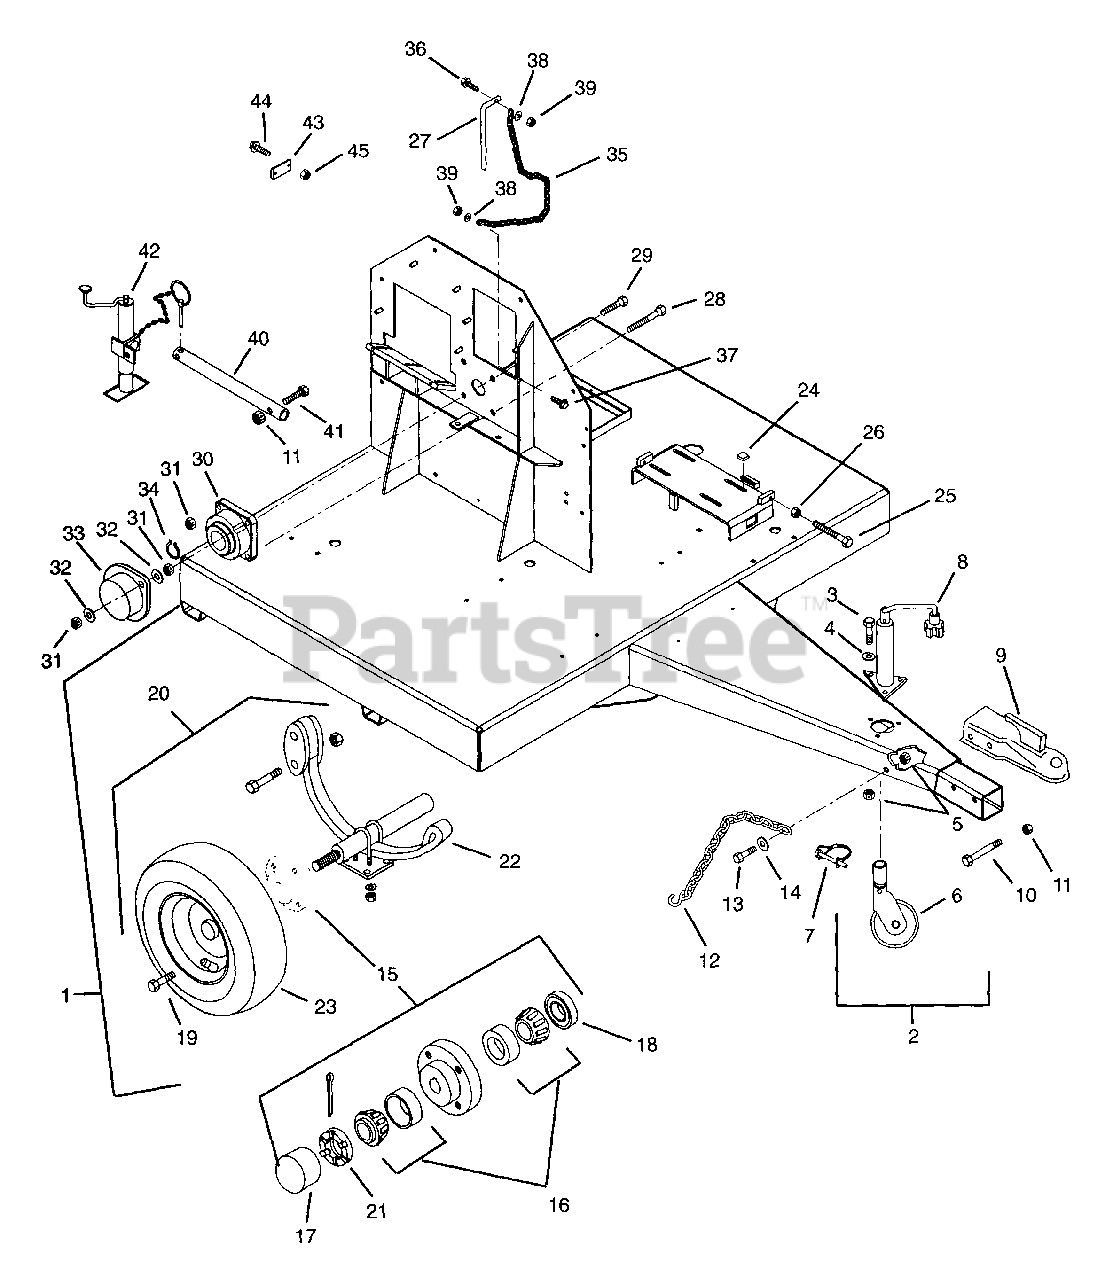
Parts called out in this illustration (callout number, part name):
1	Trailer Bed, Complete
2	Jack Assembly
3	Bolt-Hex .44-14 x 1.25 Grade 5
4	Washer-Flat-Steel .50 x 1.25 x .083
5	Nut-Locking-Center .44-14
6	Swivel Wheel
7	Quick Latch Pin, Jack Wheel
8	Pillow Jack Assembly - Less Wheel
9	2" Coupler Ball Type
10	Bolt-Hex .50-13 x 3.75 Grade 5
11	Nut-Locking-Center .50-13
12	Safety Chain,
13	Bolt-Hex .44-14 x 1.00 Grade 5
14	Washer-Flat-Steel .50 x 1.25 x .083
15	Axle Hub, Complete
16	Bearing Replacement Assembly
19	Bolt-Hex .50-20 x .75 x 1.62
20	Trailer Axle, Complete - Less Tire and Wheels
21	Nut-Slotted 1.0-14
22	Axle Spring
23	Tire and Wheel Assembly
24	Key-Straight .38 x 2.75 x .38
25	Bolt-Hex .38-16 x 3.5
26	Nut-Hex .38-16
27	Pin-Arbor Shaft Lock
28	Bolt-Lug .50-20 x 2.50
29	Bolt-Lug .50-20 x 1.50
30	Bearing-Flange 1.500 x 4 Bolt x 2.047
31	Nut-Locking-Center .50-20
32	Washer-Flat-Steel .531 x 1.06 x .095
33	Bearing Cover
34	Retaining Ring-External 1.500 x .109
35	Chain-14 Straight Link #4
36	Screw-Machine-Hex Washer Head 10-24 x 1.00
37	Screw-Machine-Hex Washer Head 10-24 x .75
38	Washer-Flat-Steel .219 x .50 x .049
39	Nut-Locking-Nylon 10-24 w/Insert
40	Tube-Jack Pivot
41	Bolt-Hex .50-13 x 3.00 Grade 5
42	Jack-2000 LB x 12.75 Screw
43	Reflector
44	Screw-Machine 10-24 x .75
45	Nut-Locking-Nylon 10-24 w/Insert
